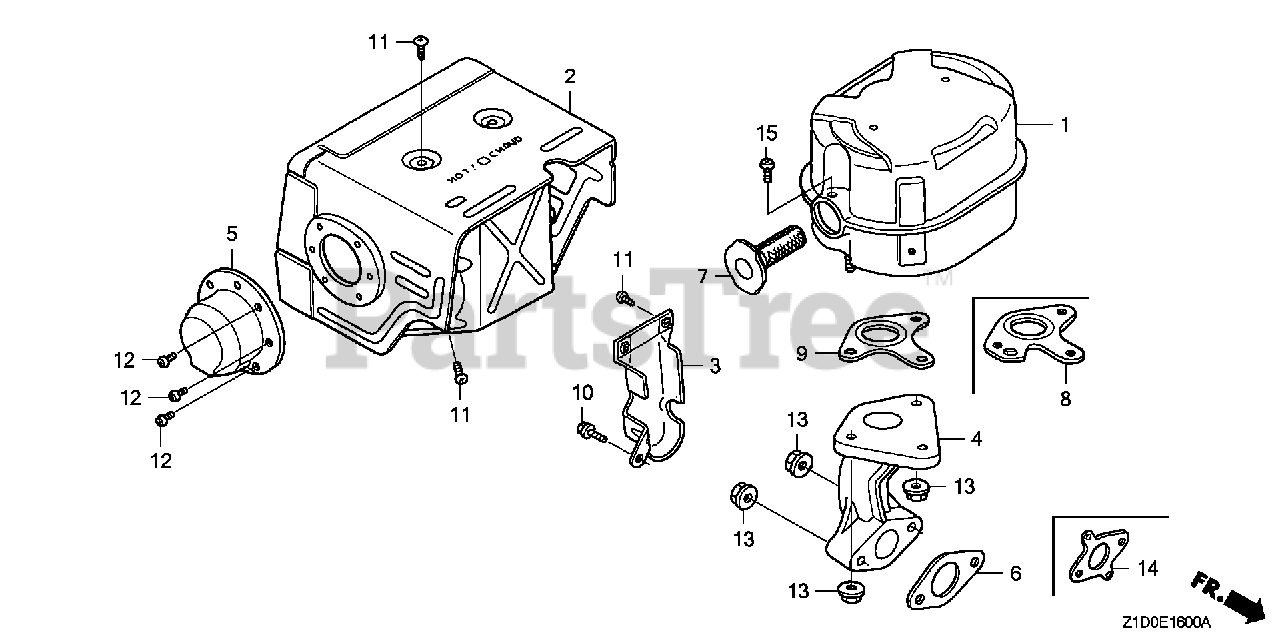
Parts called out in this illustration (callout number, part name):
1	MUFFLER
2	PROTECTOR, MUFFLER (STD)
3	PROTECTOR, EX. PIPE
6	GASKET, EX. PIPE
9	GASKET, MUFFLER (NIPPON LEAKLESS)
10	BOLT, FLANGE (6X12) (CT200)
11	SCREW, TAPPING (5X8)
13	NUT, FLANGE (8MM)
